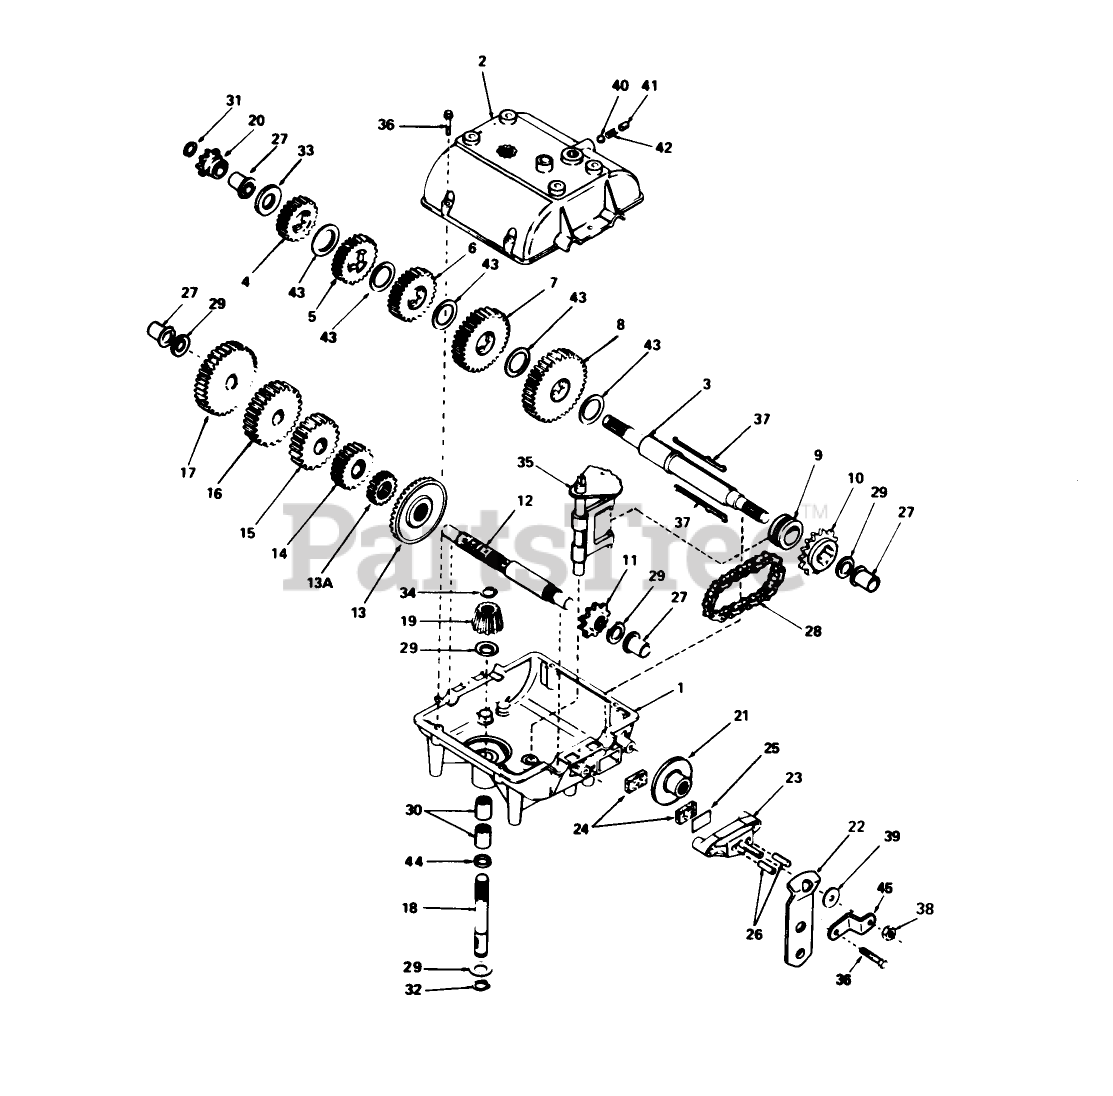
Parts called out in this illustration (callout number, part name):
1	Case-Transmission
2	Cover-Transmission
3	Shaft-Output Brake
4	Gear-Spur 20 teeth
5	Gear-Spur (22 teeth)
6	Gear-Spur, 25 Teeth
7	Gear-Spur, 30 Teeth
8	Gear-Spur, 35 Teeth
9	Collar-Shift
10	Sprocket-18 Teeth
11	Sprocket-9 Teeth
12	Countershaft
13	Gear-Bevel (42Teeth)
13A	Gear-Spur 15 Teeth
14	Gear-Spur, 20 Teeth
15	Gear-Spur, 25 Teeth
16	Gear-Spur (28 teeth)
17	Gear-Spur (30 teeth)
18	Shaft-Input
19	Bevel Pinion-Input
20	Sprocket (8 teeth)
22	Lever-Brake
23	Nozzle-Carburetor
24	Brake Pad
25	Brake Pad Plate
26	Dowel Pin
27	Bushing-Flange
28	Chain-Roller #41
29	Washer
30	Bearing-Needle
31	Piston Asm (.020 O S)
32	Ring-Snap
33	Washer
34	Ring-Retainer
35	Rod and Fork ASM
36	Ring Set (.020 O S)
38	Locknut
39	Washer
40	Ball-Steel
41	Screw-Set
42	Spring
43	Washer
44	O Ring
45	Bracket
